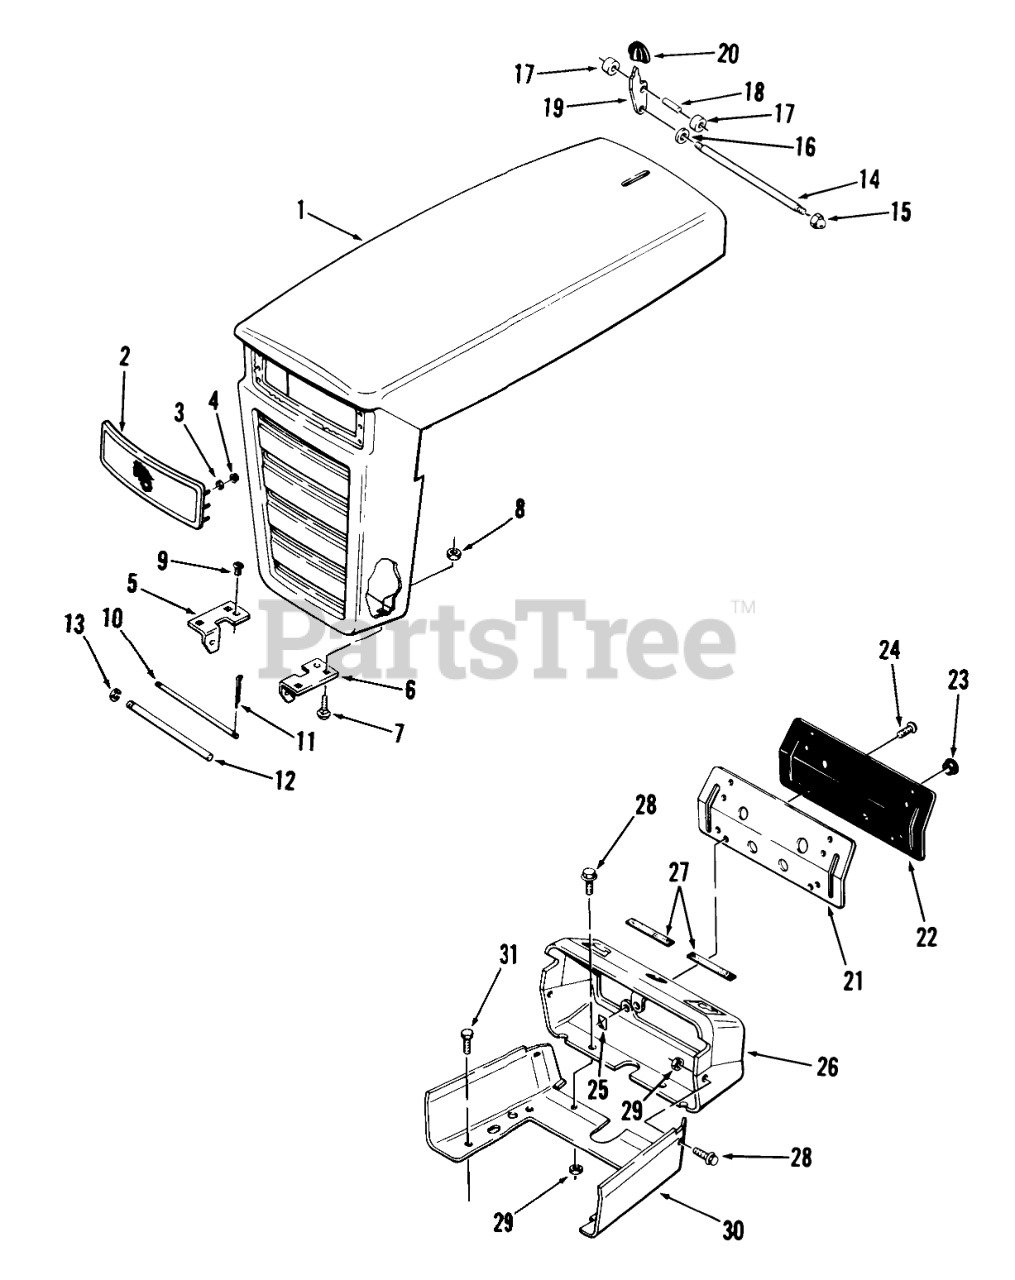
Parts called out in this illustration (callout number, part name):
2	ESCUTCHEON PLATE
3	WASHER
4	SPEED NUT
5	GRILL PIVOT BRKT
6	Bracket-Grille-L.H.
7	Bolt
8	Nut
9	GROMMET
10	ROD-HOOD STOP
11	Cotter Pin
12	GRILL PIVOT ROD
13	RING-RETAINING
14	Rod Latch
16	SPEED NUT
17	Roller
18	SPIROL PIN
19	LEVER HOOD LATCH
20	KNOB
21	BACK UP PLATE
22	PLATE-DASH INSTRUMNT
23	PLUG BUTTON
24	SCREW BLACK
25	SPEED NUT
26	HOUSING-CONTL PANEL
26	Screw
27	EDGE TRIM 4IN OF 102896
27	Lockwasher
28	Screw
28	Nut
29	Nut
30	EXTENSION-HSG CON R
